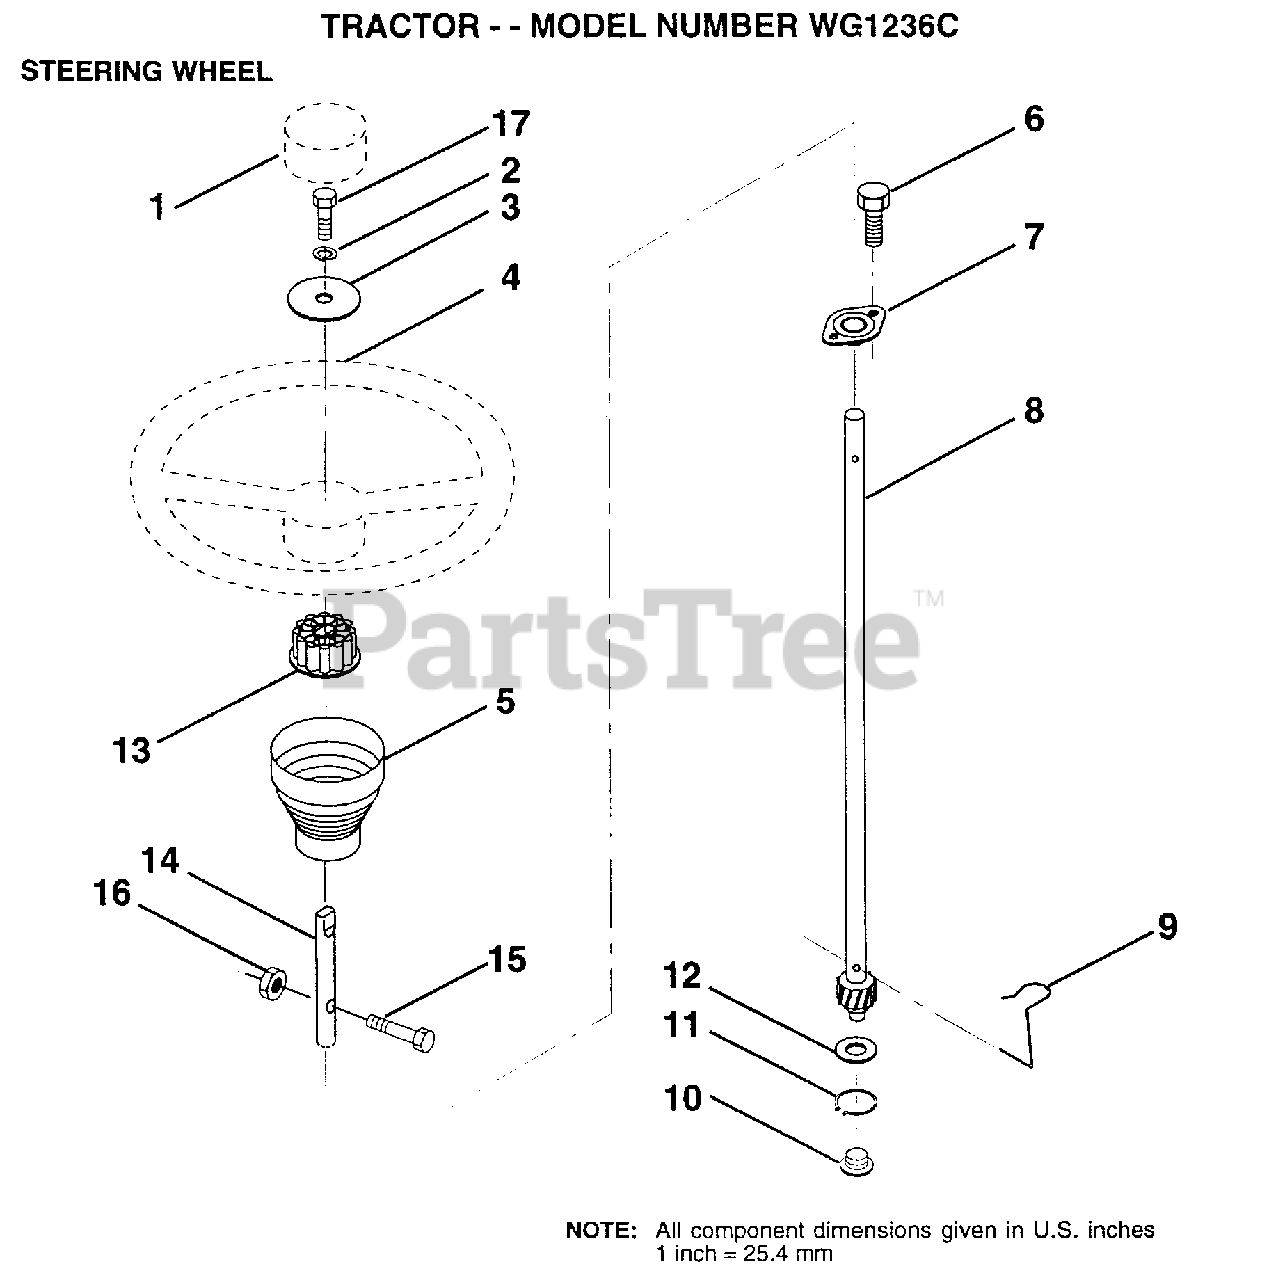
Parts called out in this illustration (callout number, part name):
1	ST WHL INSERT CAP
2	LOCKWASHER
3	WASHER T
5	SLEEVE STEERING
8	SHAFT.STEERING.LR
9	STEERING CLIP
10	BUSHING STEER LWR
11	RING
12	WASHER LT
13	ADAPTER LT
15	BOLT
16	NUT
17	BOLT
